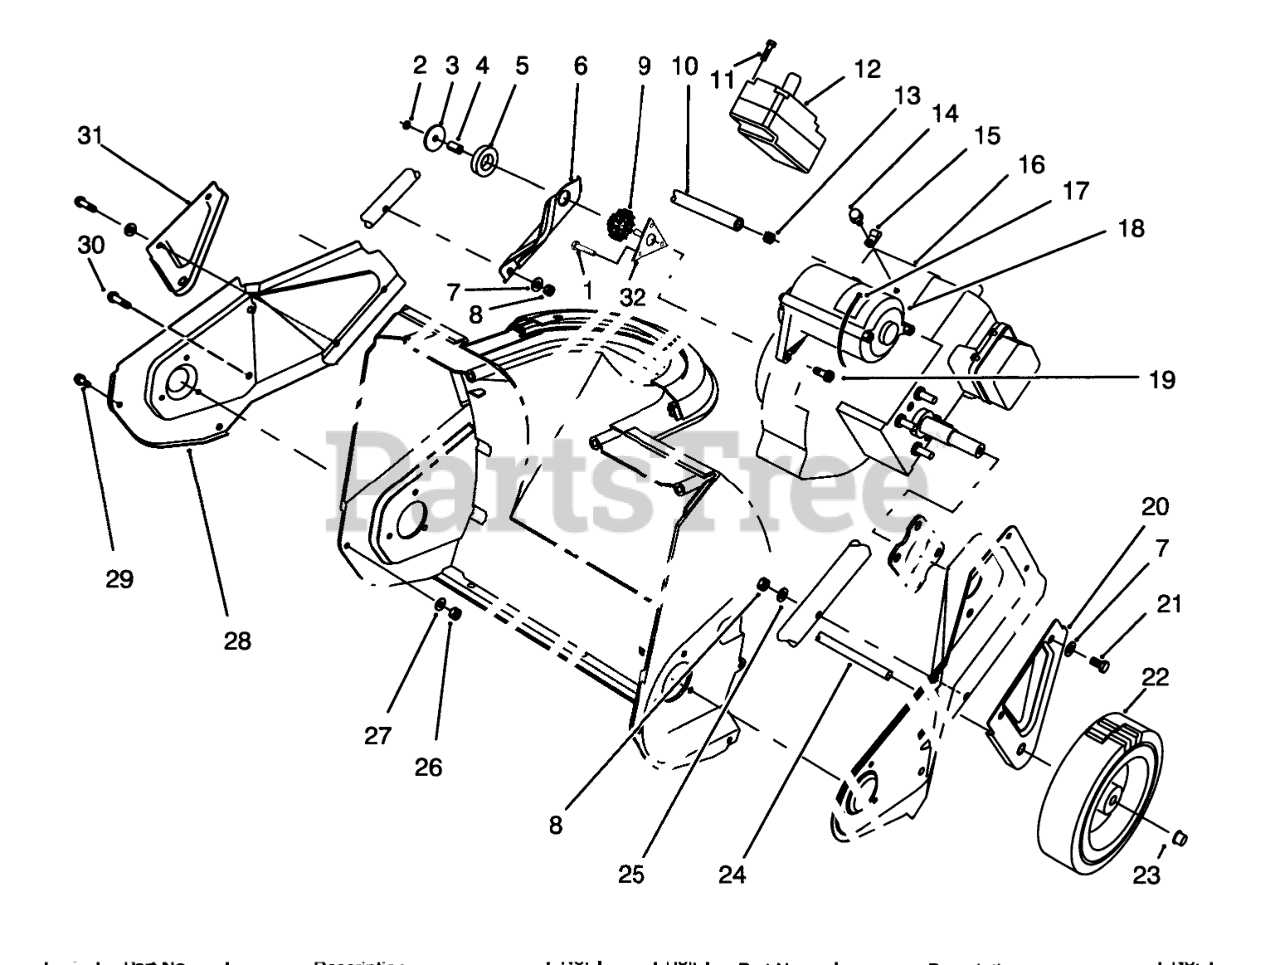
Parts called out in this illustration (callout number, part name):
1	SCREW X
2	NUT-LOCK, NI
3	WASHER-FLAT
4	SPACER-TUBULAR
5	Ring-Isolator
6	Support-Engine
7	WASHER-FLAT
8	NUT-LOCK, NI
9	BUSHING-ISOLATOR
10	LINE-GAS
11	SCREW-PLASTITE
12	ASM-Switch Housing
13	Clamp
14	SCREW-HWH
15	CLAMP
17	TIE-CABLE
18	Starter Motor Assembly
19	SCREW-HH, TORX
20	Bracket-Wheel
21	SCREW-HH
22	WHEEL
23	RETAINER-PUSH ON
25	WASHER
26	NUT-LOCK, NI
27	WASHER-FLAT
28	Sideplate-RH
30	SCREW-PLASTIC
31	Bracket-Wheel
32	BRACKET AND STUD ASM
